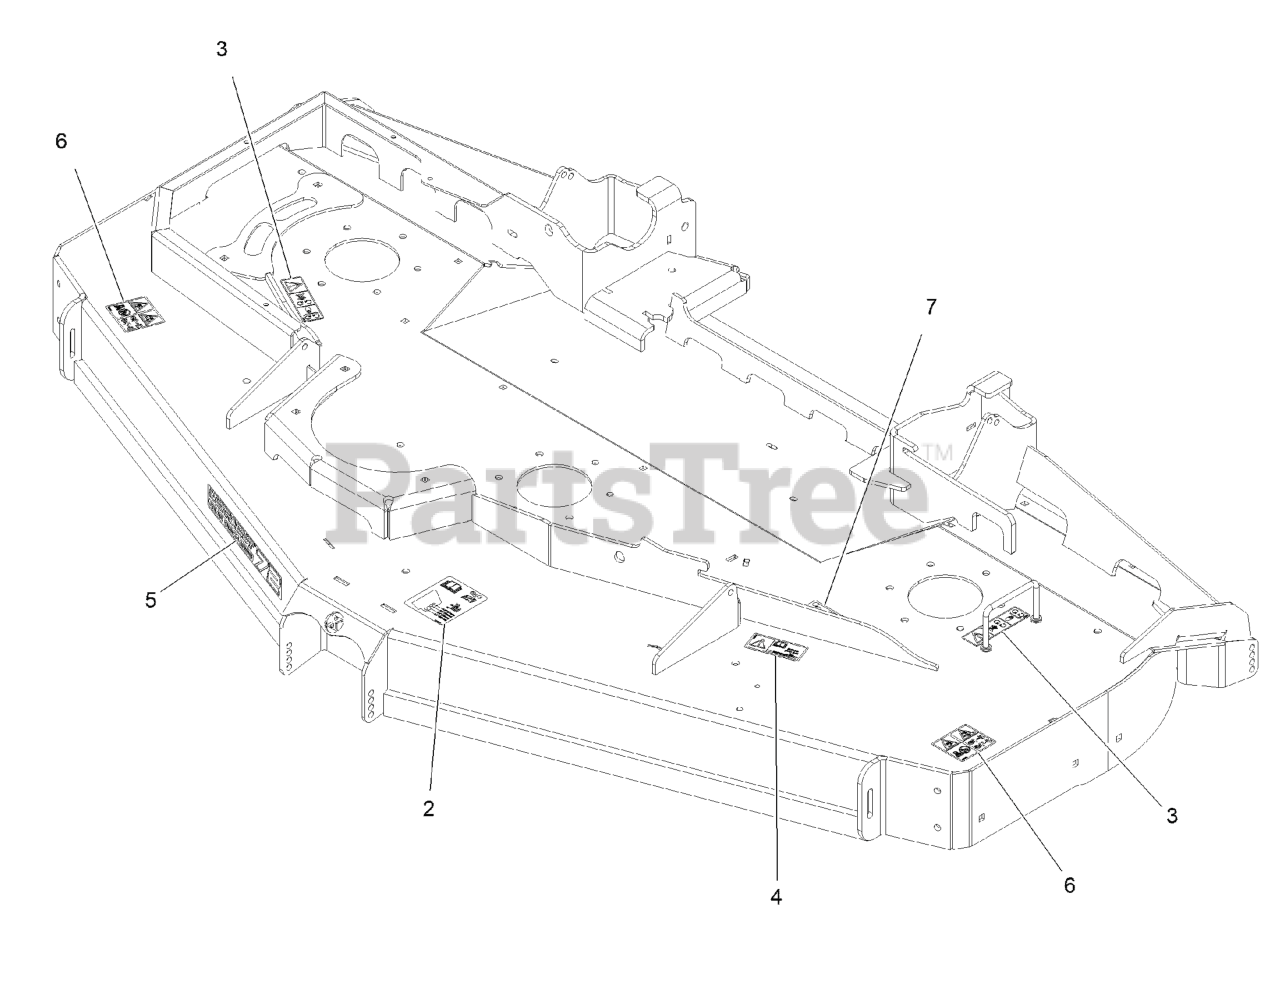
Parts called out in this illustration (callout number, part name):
2	DECAL-ROLLER, ANTI-SCALP
3	DECAL-COVER, MISSING
4	DECAL-TORQUE, BOLT
5	Decal, 72Rd
6	DECAL-DANGER, THROWN OBJECT
7	DECAL-BELT ROUTING REAR
